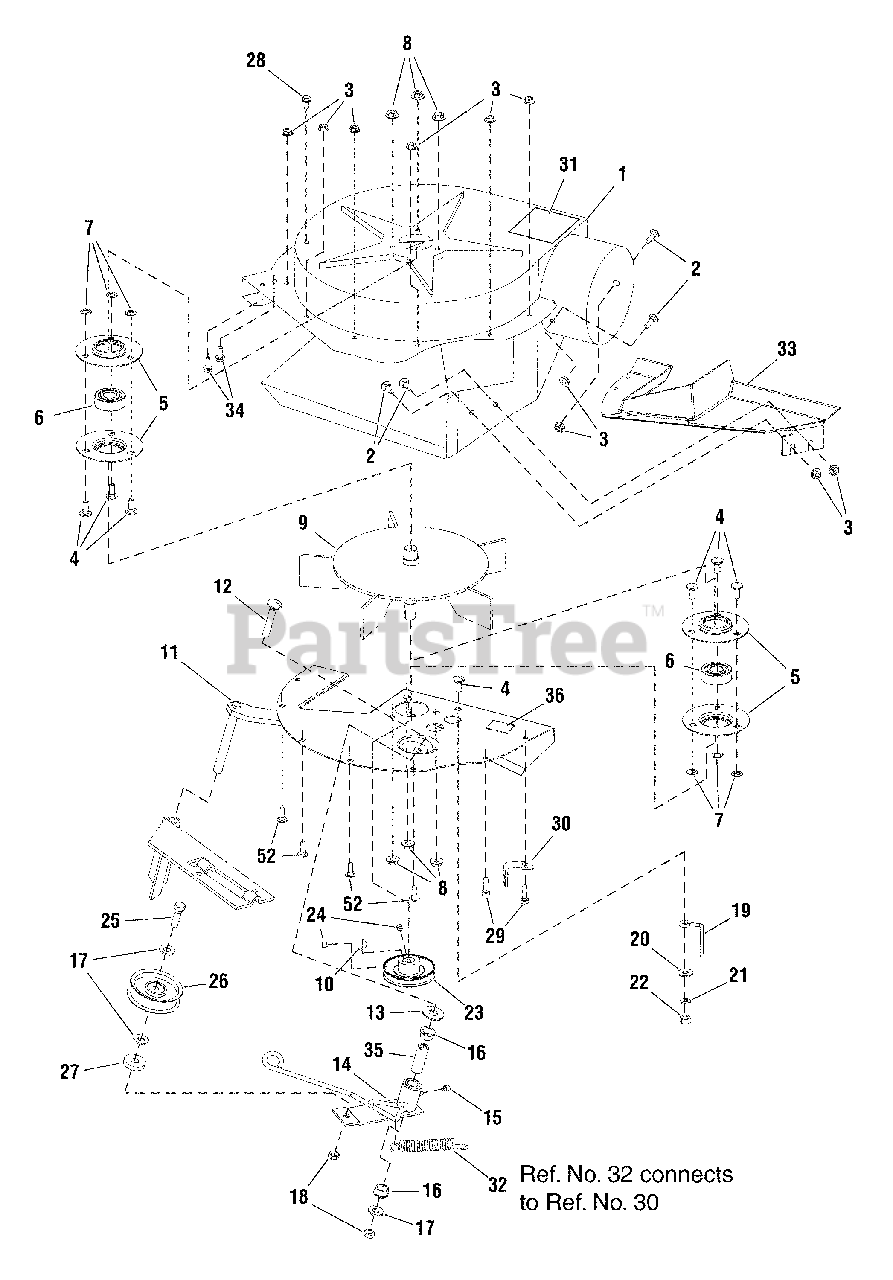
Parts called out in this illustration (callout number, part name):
1	HOUSING FAN ASSEMBLY
2	BOLT, Carriage, 1/4 - 20 x 3/4
3	NUT, Hex Flange Whiz Lock, 1/4 - 20
4	BOLT, Carriage, 5/16 -18 x 3/4
5	RETAINER, Bearing
7	PUSH NUT, 5/16
8	NUT, Hex Flange Whiz Lock
9	FAN ASSEMBLY, Five Paddle
10	KEY, Woodruff
11	PLATE ASSEMBLY
12	BOLT, Carriage, 3/8 -16
13	WASHER, Flat
14	LEVER ASSEMBLY, Turbo
15	FITTING, Lube
17	WASHER, Flat
18	NUT, Hex Center Lock Jam, 3/8 - 16
20	WASHER, Flat
21	LOCKWASHER, 5/16
22	NUT, Hex, 5/16 - 18
23	PULLEY ASSEMBLY IDLER
24	SETSCREW, Torx
25	CAPSCREW, Hex Head, 3/8 - 16 x 1-1/4
26	PULLEY ASSEMBLY IDLER
27	WASHER, Flat
28	SCREW, Washer Head Taptite, 1/4 - 20 x 1/2
29	CAPSCREW, Hex Head, 1/4 - 20 x 7/8
30	ANCHOR, Spring
31	DECAL, Danger
32	SPRING, Tension
33	PLATE, Cover
34	SCREW, Hex Washer Head, 1/4 x 3/4
36	*DECAL, Patent
52	CAPSCREW, 1/4 - 20 x 5/8
